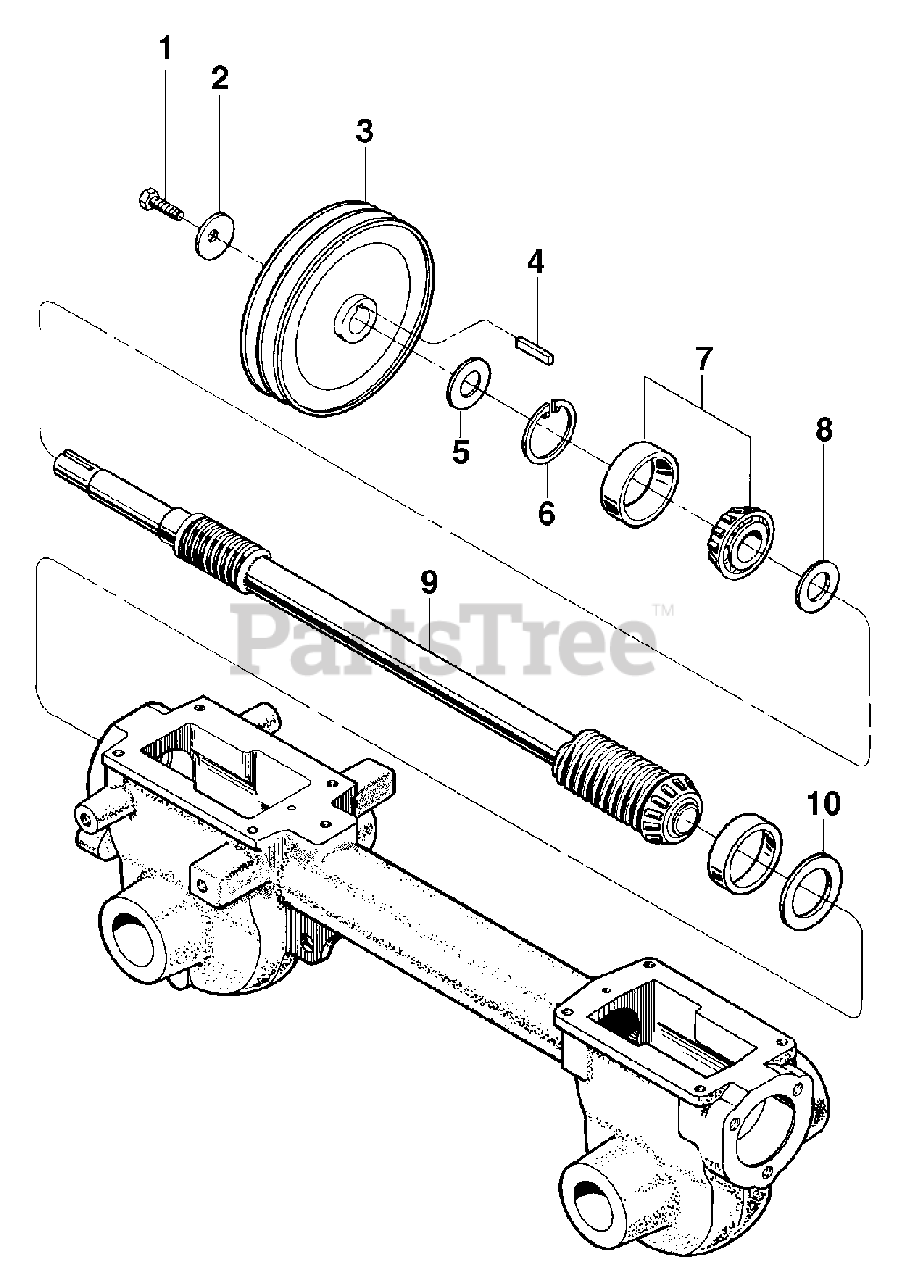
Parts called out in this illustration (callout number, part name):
1	Hex Screw, 5/16-24 x 1, Grade 5
2	Washer, Belleville
3	Pulley, Transmission
4	Key-Transmission Pulley, 3/16 x 1
5	Support Washer, Front
6	Snap Ring
7	Bearing, Tapered Roller (with race)
8	Support Washer, Rear
9	Drive Shaft Assembly
10	Shim, Rear Bearing Cap, .010 thick
